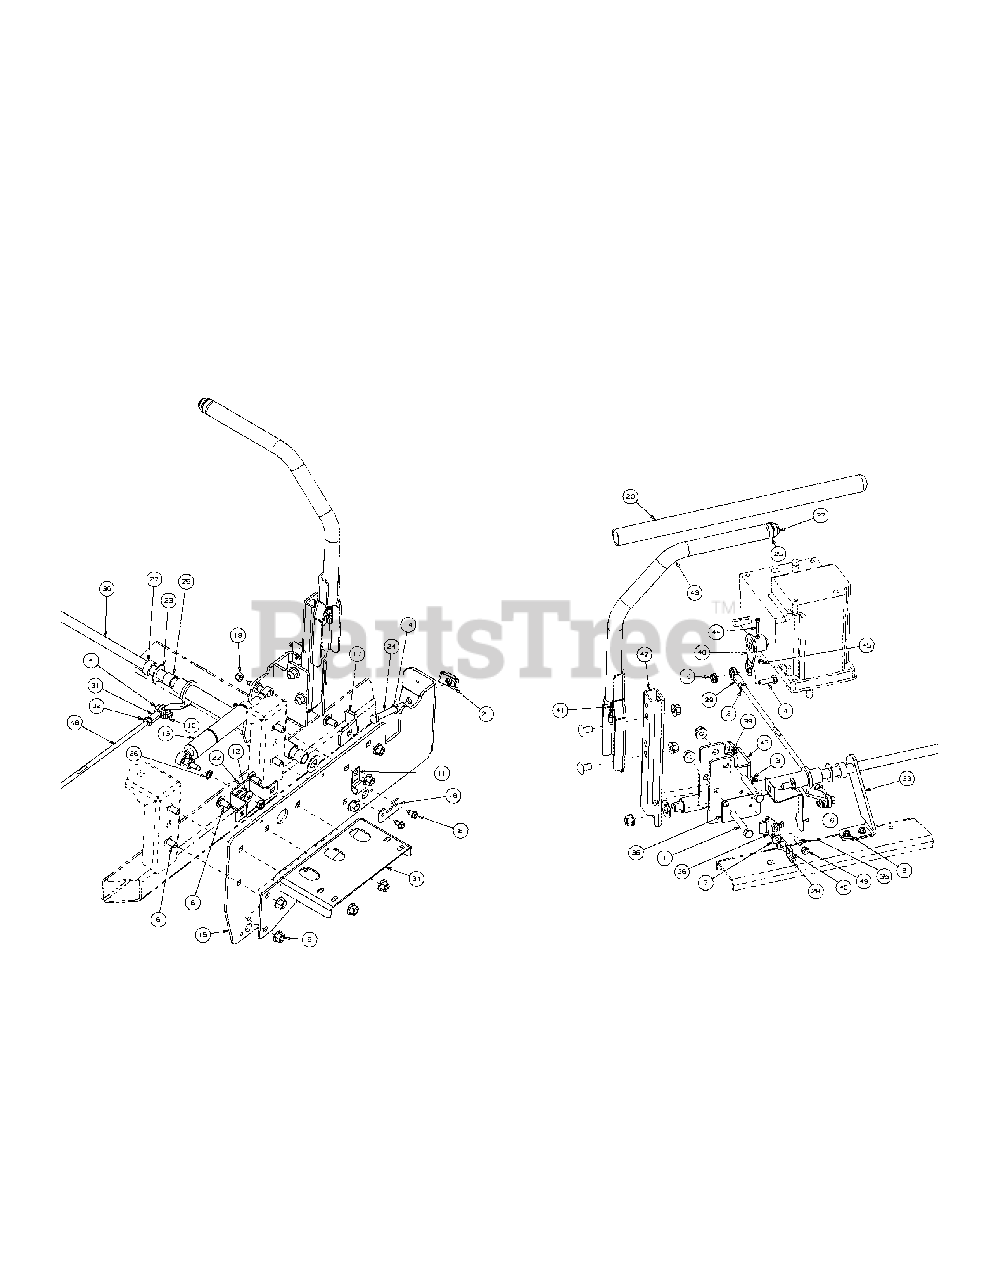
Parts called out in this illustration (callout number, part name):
1	HHCS, 3/8-16, 2.5
2	Hex Nut, 5/16-24
3	Grease Fitting, 90°, 1/4-20
4	HHCS, 5/16-18 x 1.0
5	Hex Nut, 3/8-16, Lock Flange
6	Carriage Bolt, 3/8-16 x .75 Lg.
7	Flat Washer, 1/4"
8	Screw, TT, 1/4-20, 0.5, Hex Index Washer
9	Screw, TT, 1/4-20, 0.75, Hex Index Washer
10	Nut, Lock, HexFlange, 5/16-18
11	Clip, Heat Shield
12	Belle Washer, .325 x .930 x .045
13	Cylinder Return to Neutral Kit
14	Nut, 3/8-16, Jam
15	Control Panel Mount, RH
16	Lever, Safety Switch
18	Holder Shaft, Park Brake
19	Nut, Hex, Center Lock, M8
20	Grip, 1.0
21	U-Nut, 3/8-16, .75
22	Bracket Assembly, Mount Dampener
23	Flat Washer, 5/8 Nylon
24	HHCS, 3/8-16, 3.00
25	Lock Washer, Ignition Switch
26	External Tooth Washer, 3/8
27	Shaft Collar
28	Shoulder Bolt, 1/4x1/4
29	Rod End, 5/16, Right Hand
30	Shaft Mounting Belle Crank
31	Rod End, 5/16, Left Hand
32	Hex Nut, 5/16-24, Left Hand
33	Lapbar Shaft Support
34	Valve Control Mounting Plate
35	Plunger, 1/4-20 x 3/4
36	Speed Control Adjuster Assembly, RH
37	Lapbar Switch, On/Off
38	Speed Control Detent Plate
39	Nut, 10-24, w/Star Washer
40	Grip, Speed Lever
41	Split Conduit, 1/4 Poly
42	Mounting Handle
43	Lapbar Handle Weldment, RH
44	Sockethead Capscrew,, M4 x 0.7 x 25mm
45	Nut, M4 x 0.7mm, Nylock
46	Pump Mount Bracket
47	Hub Assy, Control RH Bearing
48	Control Rod, 5/16-24, RH/LH x 13.5
49	Nut, 1/4-20, Hex
